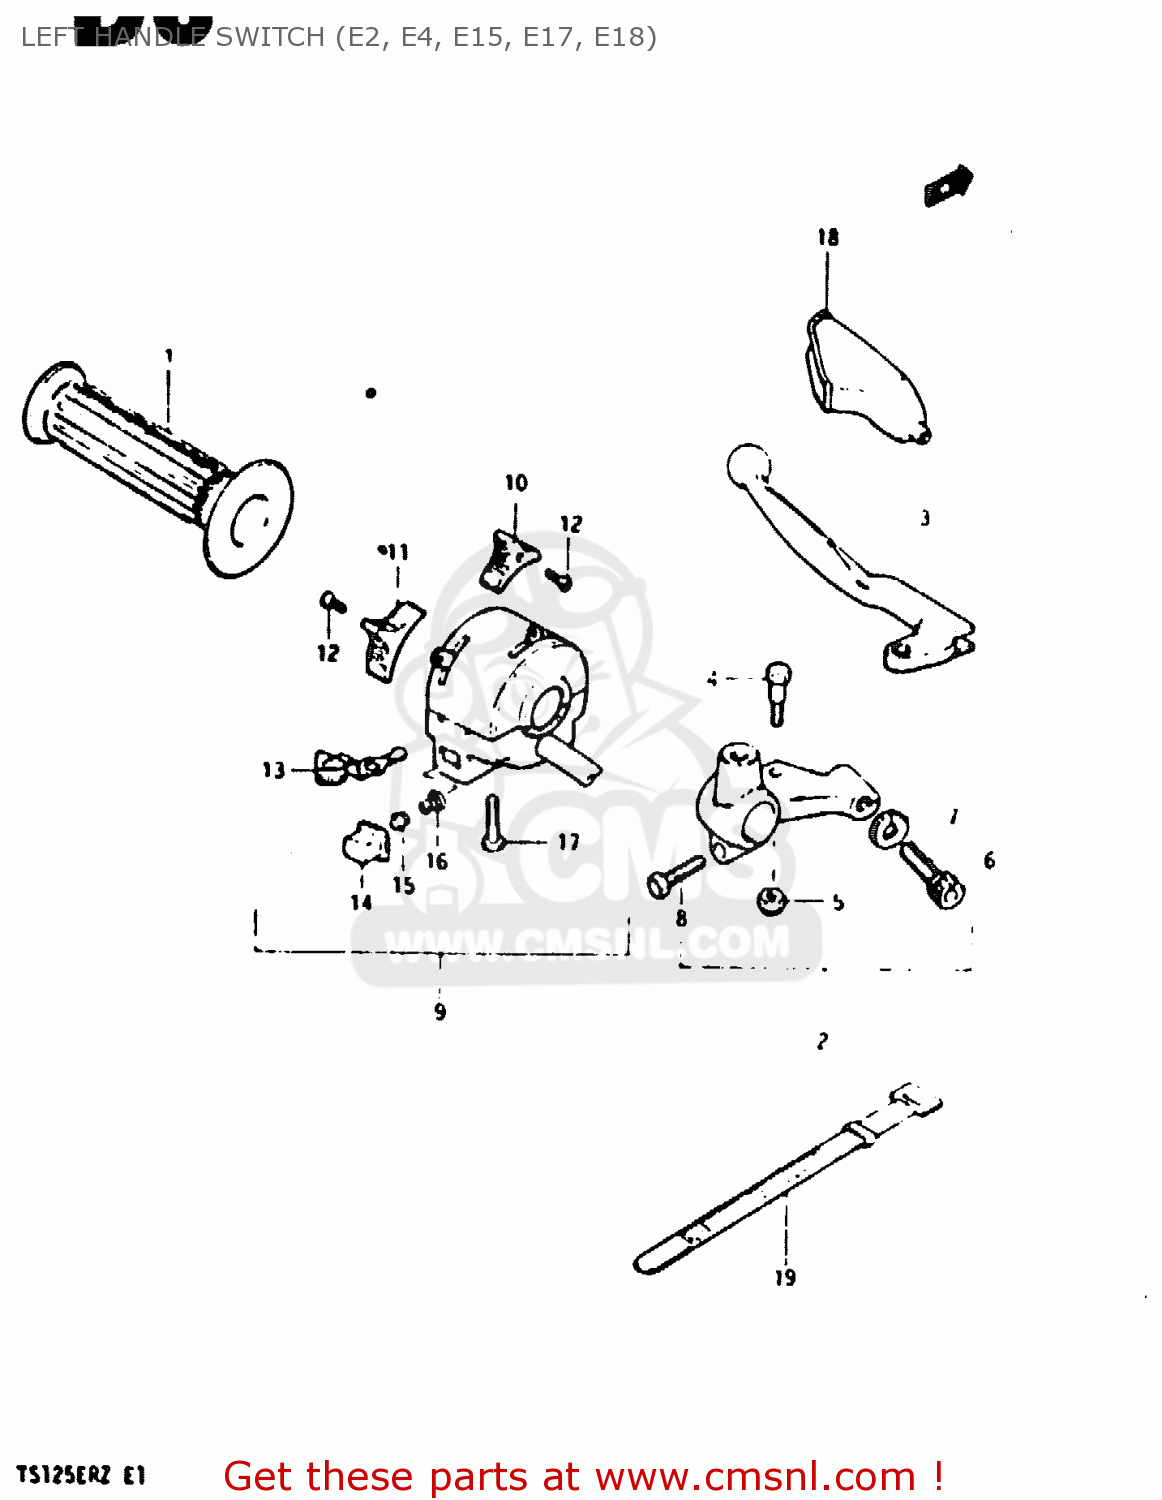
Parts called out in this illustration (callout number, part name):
1	GRIP,L
2	LEVER ASSY, CLUTCH
3	LEVER, CLUTCH
4	BOLT,LEVER
5	NUT 6MM
6	ADJUSTER,CABLE
7	NUT,CABLE ADJUSTER
8	BOLT
9	SWITCH ASSY, HANDLE LH
10	KNOB,LIGHTING SWITCH
11	KNOB, DIMMER
12	SCREW
13	KNOB,TURNSIGNAL
14	BUTTON,HORN
15	CONTACT
16	SPRING
17	SCREW
18	COVER,CLUTCH LEVER
19	CLAMP(L:120)
